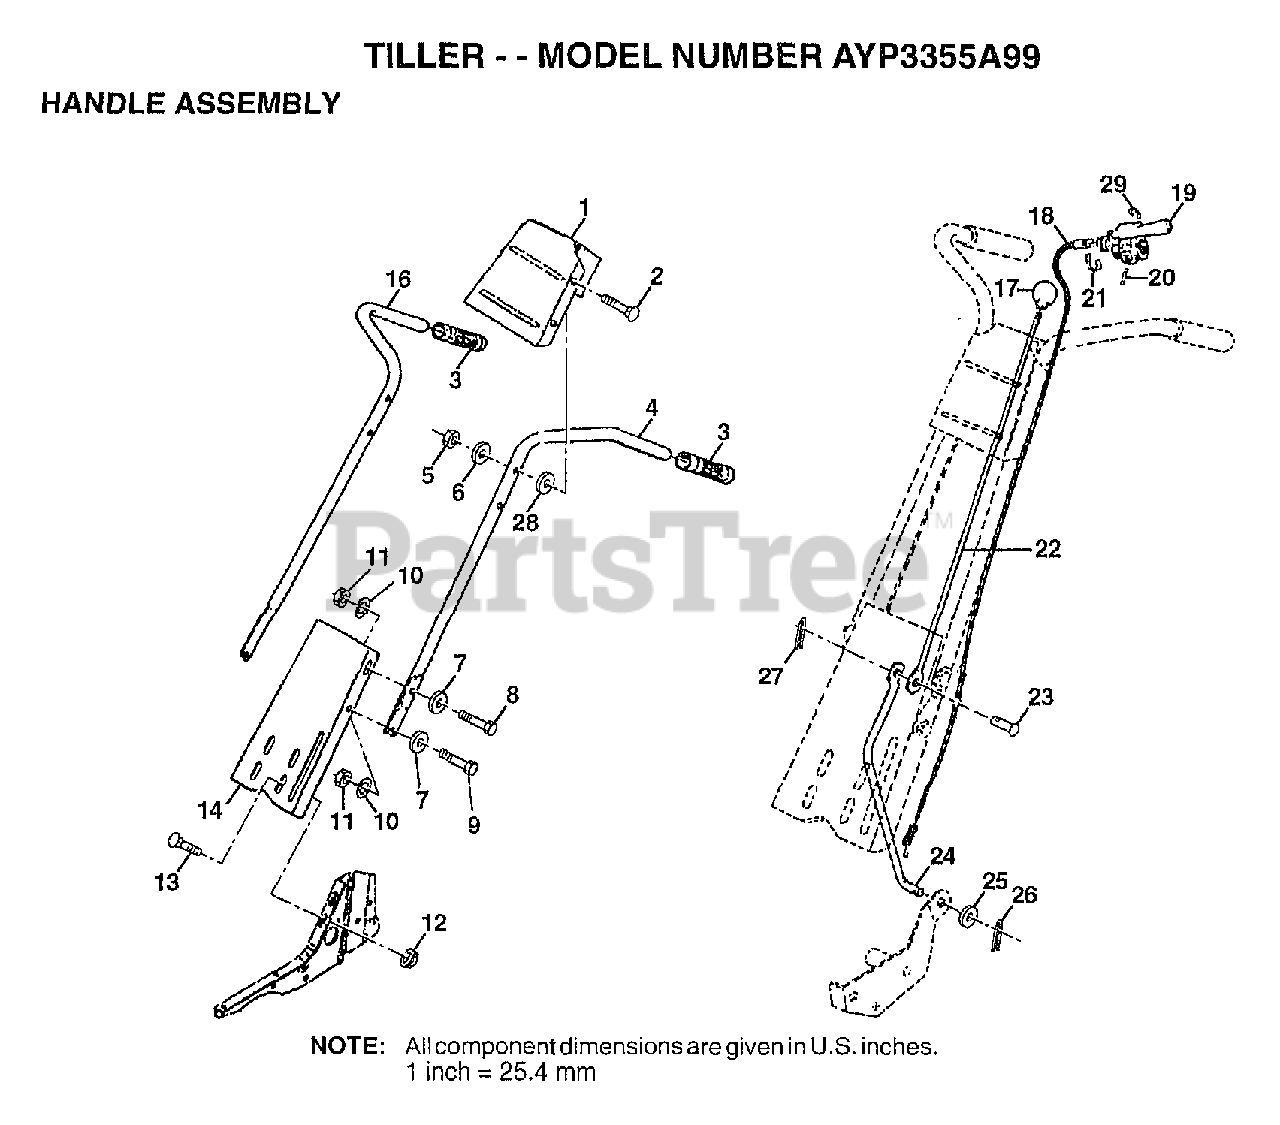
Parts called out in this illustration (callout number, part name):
1	HANDLE BRKT
2	BOLT
4	HANDLE.LH
6	WASHER
7	WASHER
9	BOLT
10	LOCKWASHER
11	NUT.HEX.5/16-18
12	NUT
13	BOLT
17	KNOB T(3/8 HOLE)
18	CABL.CLUTCH.49.88
19	LEVER CONTRL TINE
20	"PIN PIVOT,GROOVED"
21	E-RING
22	ROD.REVERSE.UPPER.22
23	RIVET.RD.HD.DRILL
24	REVERSE ROD TI
25	WASHER
26	COTTER PIN
28	WASHER
29	RETAINER RING
